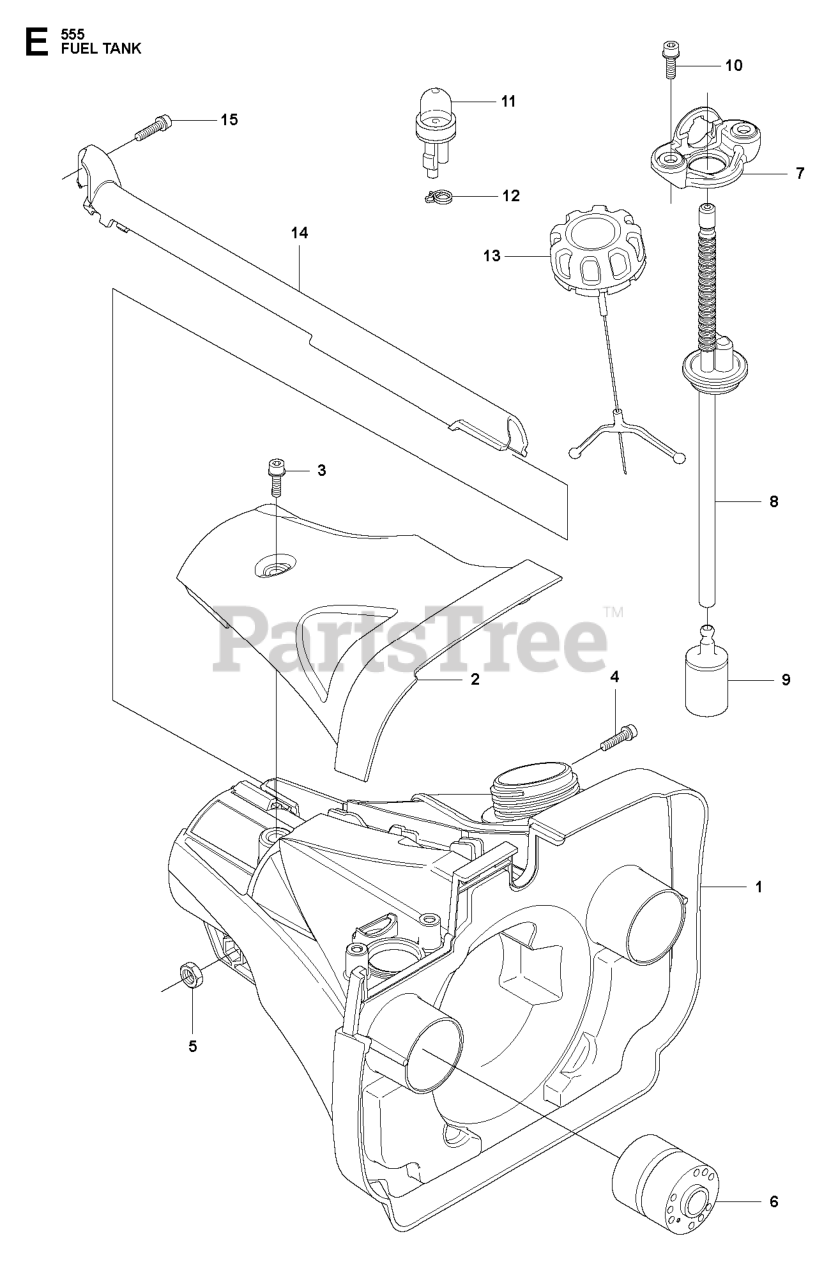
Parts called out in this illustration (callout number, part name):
2	COVER
3	SCREW IHSCFM
6	ANTIVIBE ELEMENT
9	RP FUEL FILTER
11	AIR PURGE BUBBLE
12	HOSE CLAMP
14	WIRING PROTECTION
15	SCREW IHSCFM
